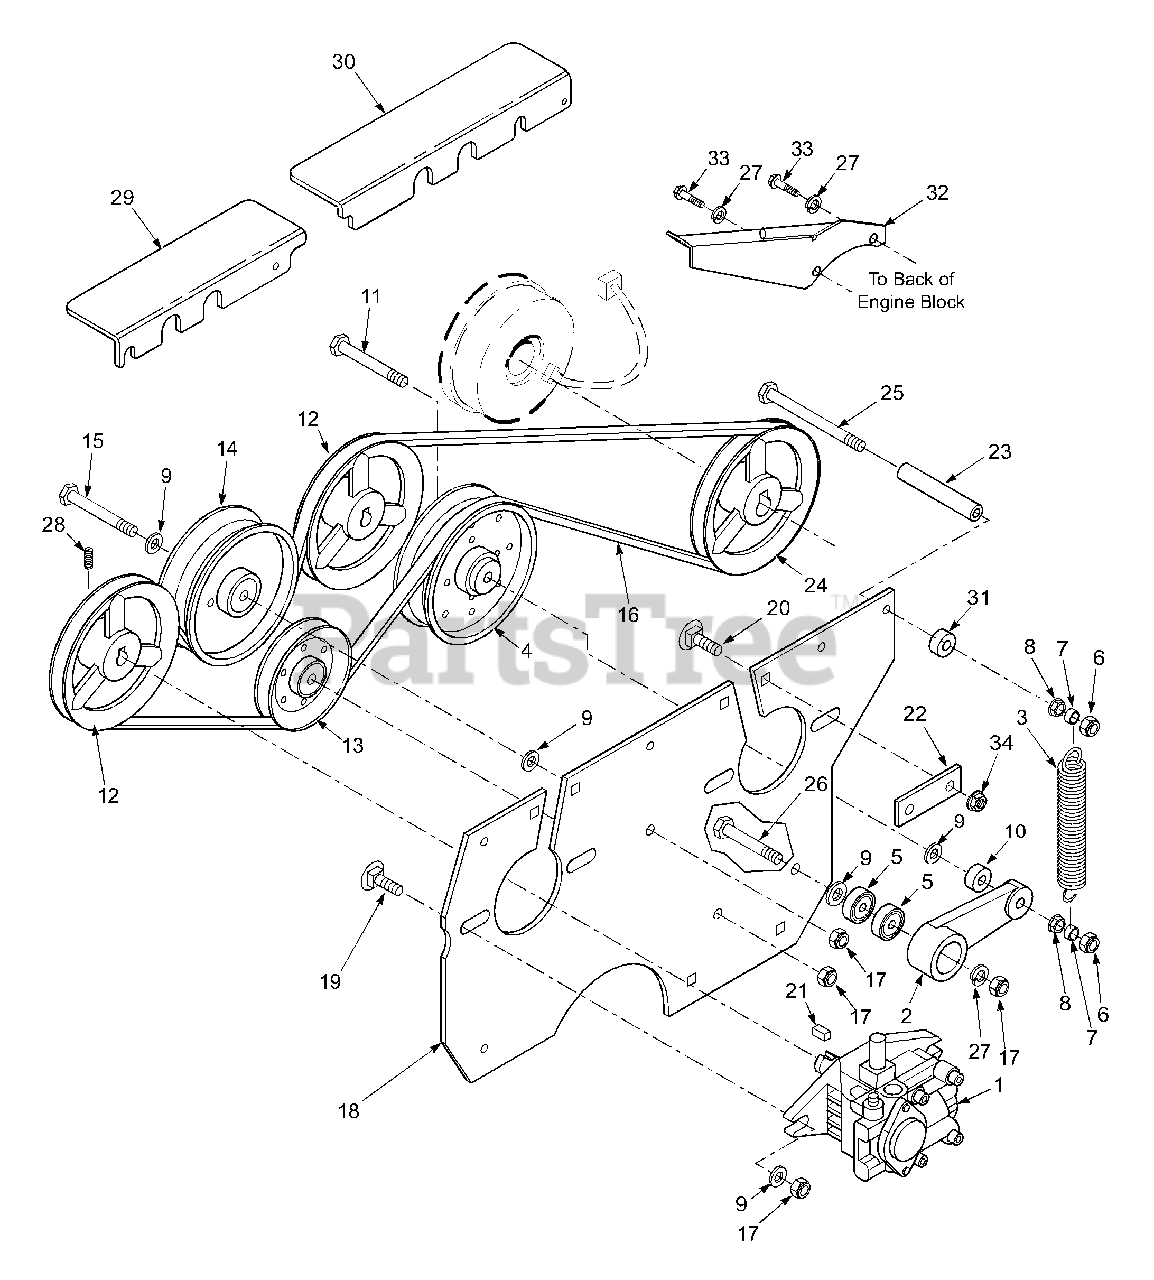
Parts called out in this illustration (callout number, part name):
1	Pump, Hydraulic
2	Idler, Arm
3	Spring, Idler
4	Pulley, Idler
5	Bearing, Idler Arm
6	Nut, 3/8-16 Center Lock
7	Spacer
8	Nut, 3/8-16 Serrated Flange
9	Washer, Flat 3/8"
10	Spacer
11	Bolt, 3/8-16 x 3.0"
12	Pulley, 5.45" OD
13	Pulley, 4" OD
14	Pulley, 4" OD
15	Bolt, Hex Head 3/8-16 x 2.5"
16	Belt, Pump Drive
17	Nut, Elastic Stop 3/8-16
18	Plate, Pump Mounting
19	Bolt, Carriage 3/8-16 x 1.5"
20	Bolt, Carriage 5/16-18 x .75"
21	Key, 5mm x 5mm x 25mm
22	Plate, Keeper
23	Spacer
24	Pulley, 5.45" OD
25	Bolt, 3/8-16 x 6"
26	Bolt, Hex Head 3/8-16 x 2.5"
27	Washer, Lock 3/8"
28	Setscrew, .312-18 Thread
29	Cover, Belt Front
30	Cover, Belt Rear
31	Spacer
32	Heatshield
33	Bolt, Carriage 3/8-16 x 1"
34	Nut, Serr. Flange 5/16-18
